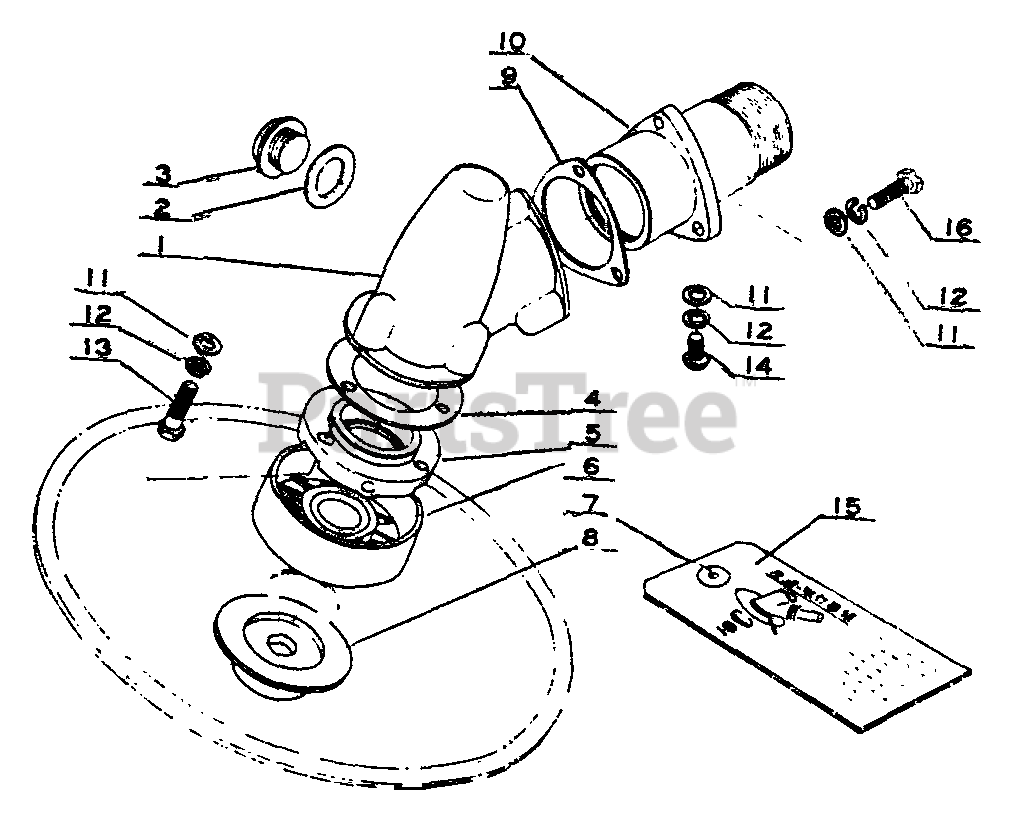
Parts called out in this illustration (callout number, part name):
1	CASE, GEAR
2	PACKING, INJECT PLUG
3	PLUG, INJECT GREASE
4	GASKET, GEAR CASE
5	BEARING HOLDER (B)
6	FITTING PLATE (A)
8	FITTING PLATE (B)
9	GASKET, GEAR CASE
10	BEARING HOLDER (A)
11	WASHER, FLAT 5.5×10×0.8
12	WASHER, SPRING 5
13	BOLT - 5×16
14	SCREW 5×8
16	SCREW 5×18
